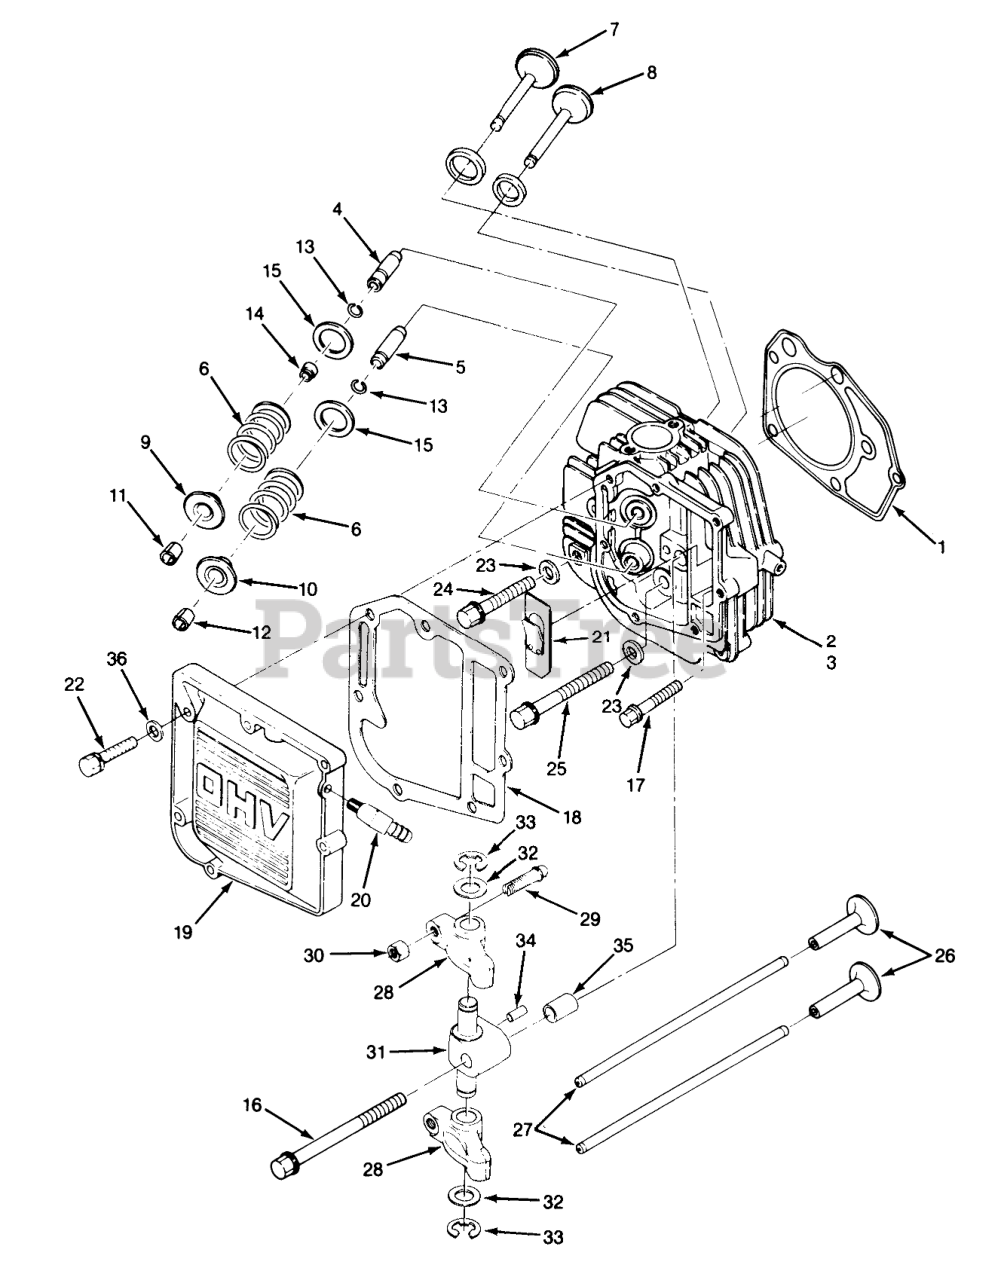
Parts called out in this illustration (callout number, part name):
1	GSKT-CYL HEAD
2	Cylinder Head Assembly (Incl. Ref. #4-15)
3	Cylinder Head Assembly (Incl. Ref. #4-5)
4	GUIDE-VALVE INTAKE
5	GUIDE-VALVE EXHAUST
6	SPRING-VALVE
7	VALVE-INTAKE MKD IN
8	VALVE-EXHAUST MKD EX
9	RETAINER-VLV SPG IN
10	RETAINER-VLV SPG EX
11	Lock-Intake
12	LOCK-VALVE EXHAUST
13	RING-VALVE GUIDE
14	Seal-Intake
15	WASHER-VALVE SPRING
16	BLT-CYL HD M10X125MM
17	BLT-CYL HD M8X50MM
18	Seal
19	Cover-Valve
20	ELBOW-90 DEGREES
21	BREATHER
22	SCRW-CP SH M6X25MM
23	WASHER-FLAT M10
24	BLT-CYL HD M10X66MM
25	BLT-CYL HD M10X66MM
26	TAPPET
27	ROD-PUSH
28	Rocker Arm Assembly (Incl. Ref. #29-30)
29	SCRW-LASH ADJUSTING
30	NUT-LASH ADJUSTING
31	SHAFT-ROCKER ARM
32	Rocker Arm Washer
33	CLIP-RETAINER
34	PIN-DOWEL
35	PIN-DOWEL HOLLOW
36	Washer
